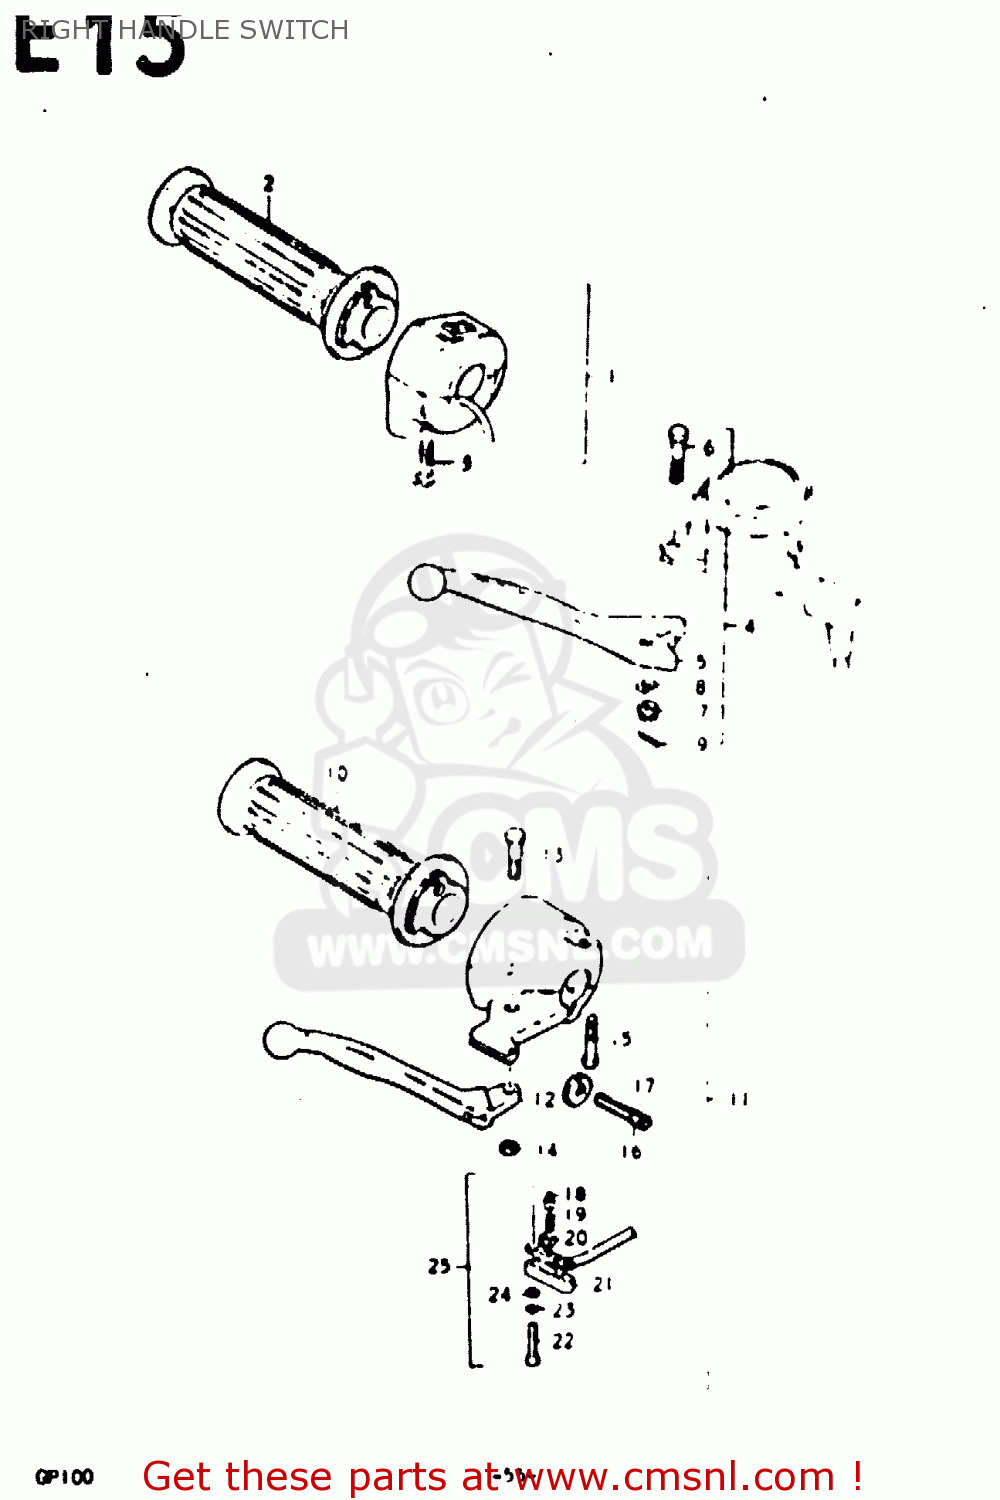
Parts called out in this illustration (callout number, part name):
1	GRIP ASSY, THROTTLE
2	GRIP,THROTTLE
3	SCREW
4	LEVER ASSEMBLY,BRAKE
5	LEVER,BRAKE
6	BOLT,LEVER
7	NUT 6MM
